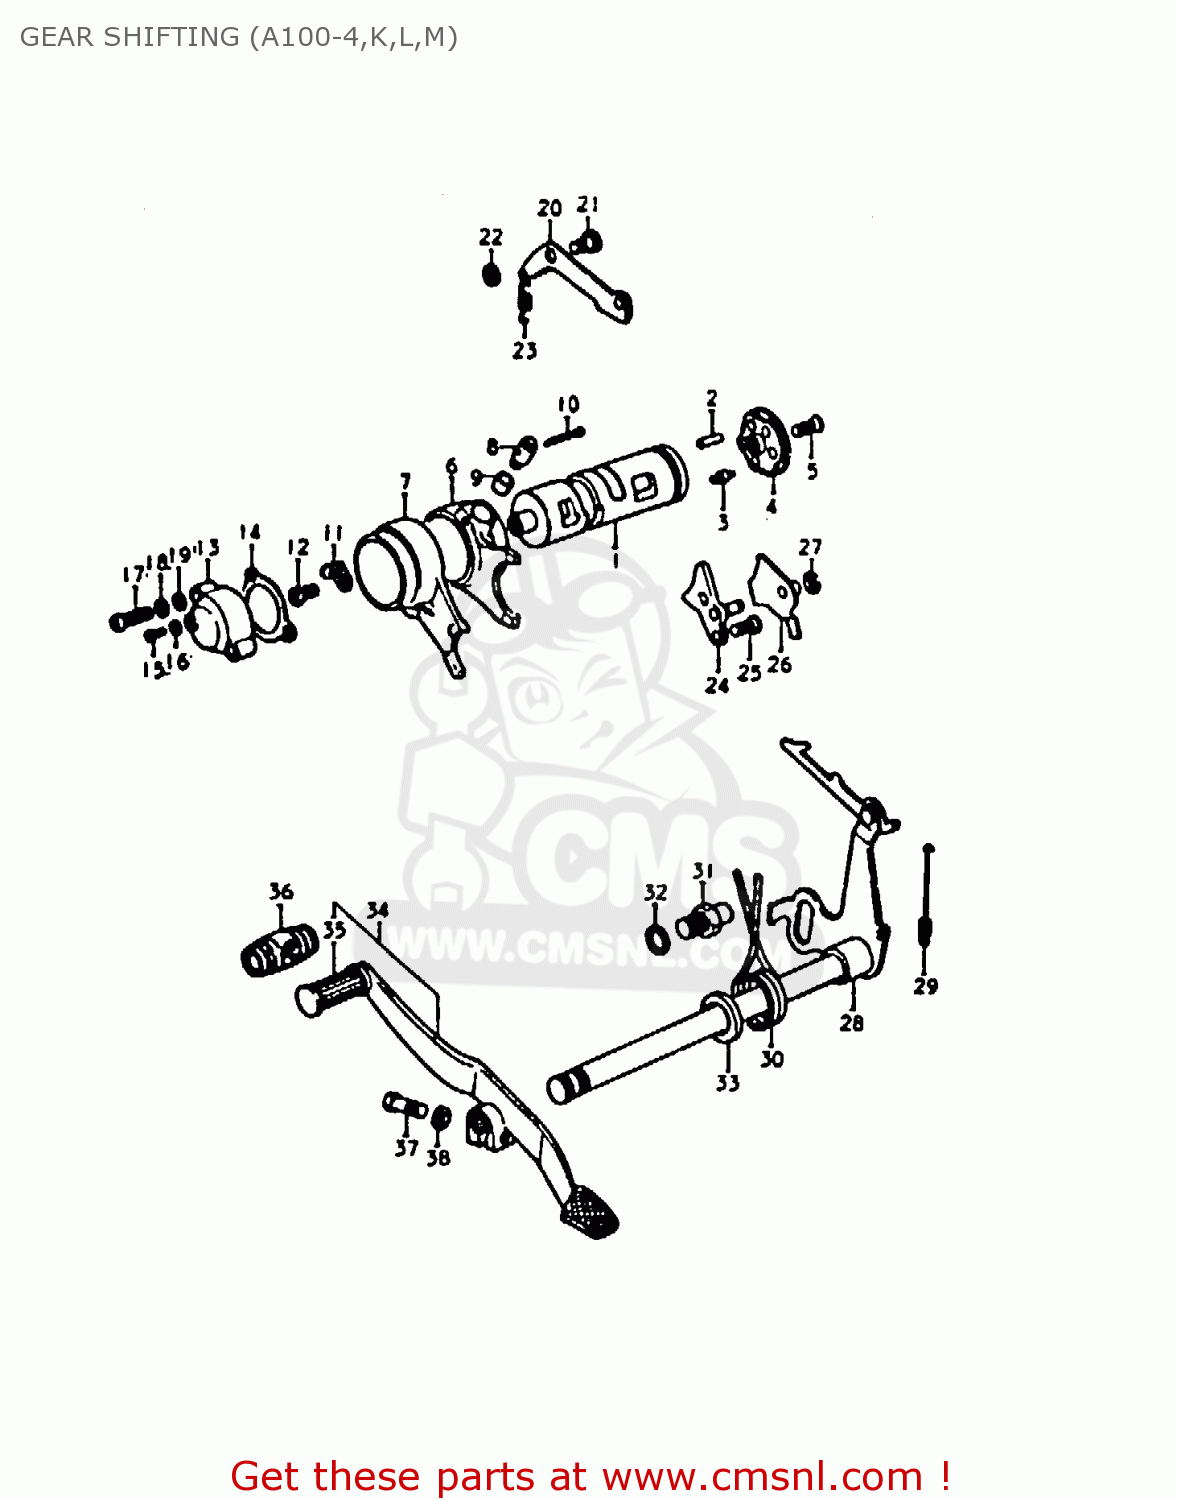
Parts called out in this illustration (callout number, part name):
1	CAM,GEAR SHIFT
2	PIN(4X20)
3	PIN
4	PLATE,GEAR SHIFT CAM STOPPER
5	SCREW
6	FORK,GEAR SHIFT NO.1
7	FORK,GEAR SHIFT NO.2
8	PIN
9	SPACER
10	PIN 25X20
11	CONTACT,GEAR SHIFT SWITCH
12	SCREW
13	SWITCH,NEUTRAL INDICATOR
14	GASKET,GEAR SHIFT SWITCH (NAS)
15	SCREW
16	WASHER
17	SCREW
18	LOCK WASHER
19	WASHER
20	STOPPER,GEAR SHIFTING
21	BOLT(6X16.1)
22	WASHER(6.5X16X2.3)
23	SPRING
24	GUIDE,GEAR SHIFT CAM
25	SCREW
26	PAWL,GEAR SHIFT CAM STOPPER
27	E RING
28	SHAFT,GEAR SHIFT
29	SPRING
30	SPRING
31	STOPPER,GEAR SHIFT ARM
32	LOCK WASHER
33	OIL SEAL
34	LEVER ASSY,GEAR SHIFT
35	RUBBER,GEAR SHIFT PEDAL
37	BOLT
38	LOCK WASHER
